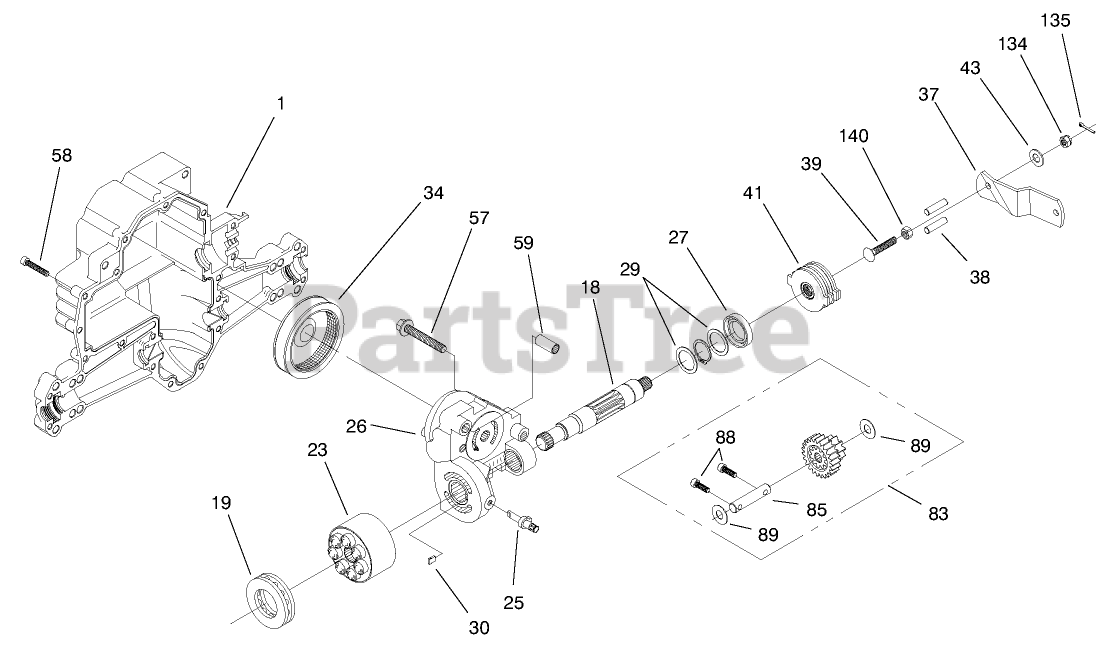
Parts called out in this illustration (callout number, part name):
18	SHAFT - MOTOR
19	BEARING-THRUST
25	ACTUATOR-BYPASS
27	SEAL - LIP
28	RING - RETAINING
29	WASHER
30	PLATE-BYPASS
37	LEVER - BRAKE
38	PIN - ACTUATING
39	BOLT 5/16-18 X 1-3/4
41	KIT-BRAKE ROTOR/STATOR
43	WASHER-PIVOT
83	ASM-JACKSHAFT/PINION GEAR
89	WASHER
134	NUT-CASTLE
135	PIN-COTTER
140	NUT-LOCK, NI
